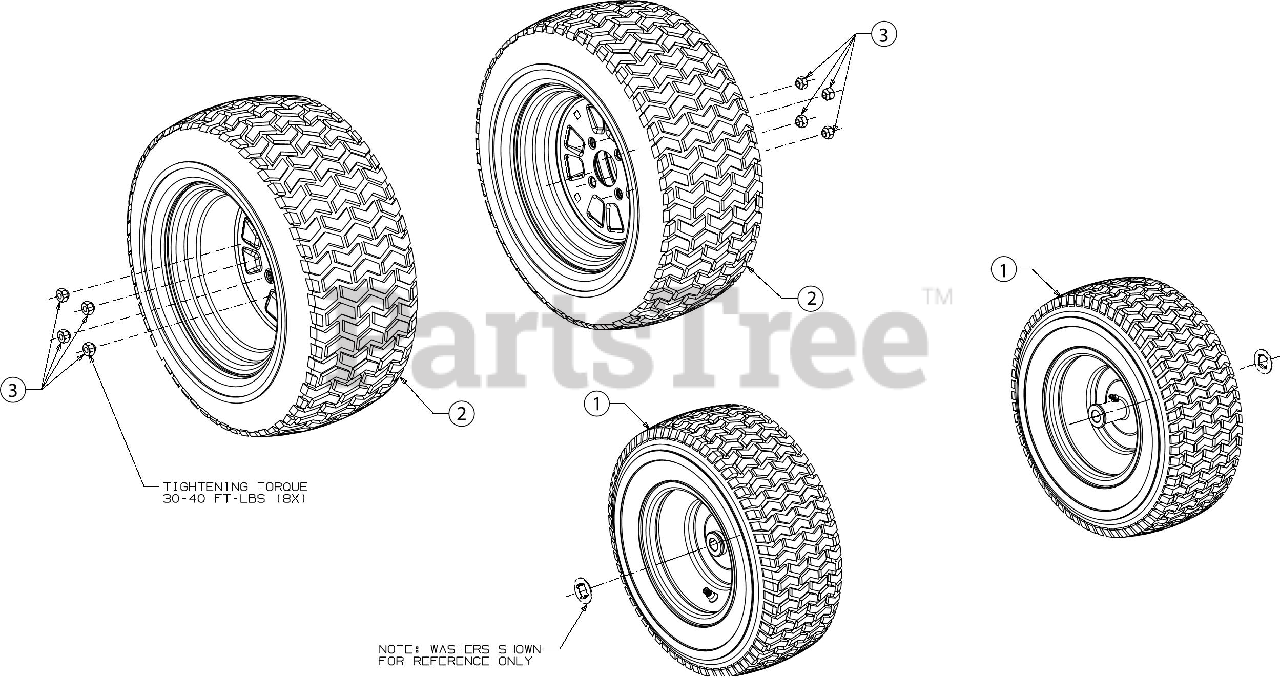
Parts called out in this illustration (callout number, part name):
1	WHEEL ASSEMBLY (16 x 6.5 x 8)
2	WHEEL ASSEMBLY (22 x 9.5 x 12)
3	LUG NUT 7/16-14
